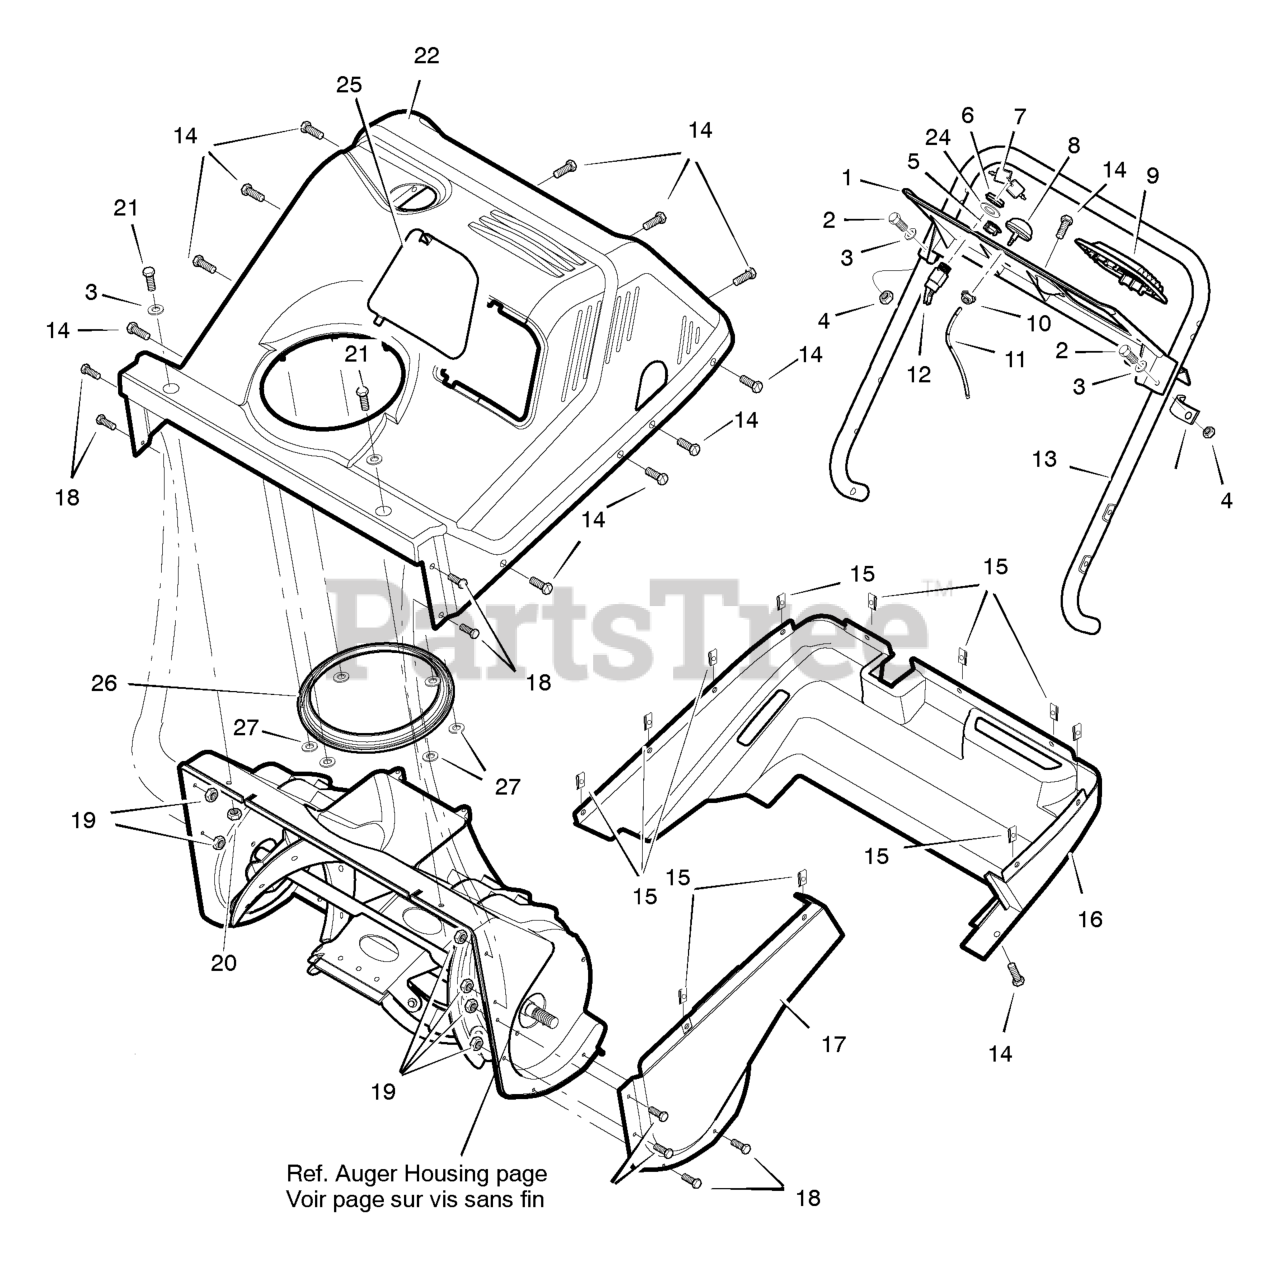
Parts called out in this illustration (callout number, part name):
1	Panel, Control
2	Screw 1/4-20 x 1.25
3	Washer
4	Nut,1/4-20
5	Bushing, Chute Crank
6	Nut, 5/8-32
7	Keys & Ring, Starter
8	Bulb, Fuel Primer
9	Panel, Cover Access
10	Nut, Keps 1/4-20
11	Hose, Primer 9.5"
12	Switch, Ignition
13	Handle, Lower
14	Screw 1/4-14 x .75
15	J-Nut 1/4-10
16	Cover, Bottom
17	Cover, Belt
18	Screw 10-24 x .5
19	Locknut, Hex 10 -24
20	Locknut, Hex 1/4-20
21	Screw 1/4-20 x .63
22	Cover, Top
24	Washer
25	Cover, Oil Access
26	Gasket, Chute Ring
27	Push Nut
28	Clamp, Cable
